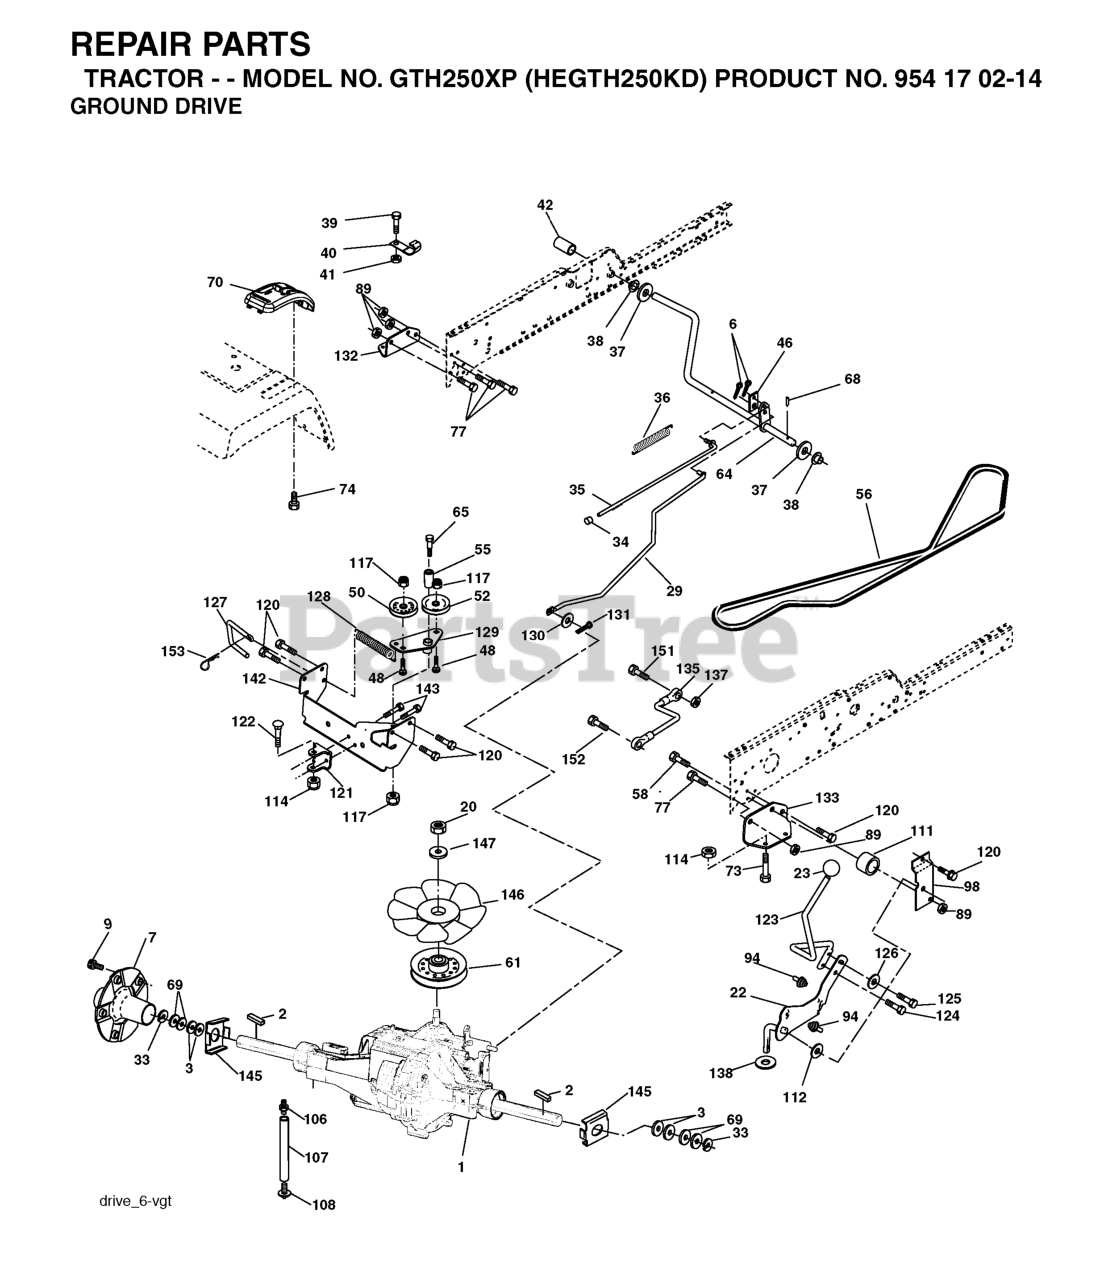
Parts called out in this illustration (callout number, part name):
2	KEY 1/4 X 2.5
6	COTTER PIN
7	HUB ASMBLY
20	NUT.HEX.1/2-20
22	LOWER SHIFT LEVER ASM
23	KNOB.DELUXE.(PISTOL.GRIP).BLAC
29	BRAKE, ROD
33	E RING HYT
34	PLUNGER CAP
35	PARKING BRAKE ROD
36	SPRING DRIVE GROUND
39	Screw, Fin. #10-24 x 1
40	ACTUATOR INTERLOCK SWITCH
41	Nut Centerlock 10-24 unc
42	PEDAL COVER
46	RETAINER SPRING
50	FLAT IDLER PULLEY
52	IDLER PULLEY
55	BEARING LT (2 2)
56	BELT, V GROUND DRIVE
58	BOLT.HEX.7/16-14.FINISHED
61	PULLEY, TRANSAXLE
64	SHAFT.ASM.PEDAL.BRAKE
65	BOLT.SHLDR.3/8-16
68	ROLL PIN STD
70	CONSOLE AUTOMATIC YT.GT
73	BOLT HEX FLGHD 5/16-18X3 GR. 5
74	SCREW.HI-LO.CONSOLE
77	BOLT FIN HEX 7/16-14 X 1
89	Nut, Crownlock Hex 7/16-14 unc
94	FASTENER.XMAS.TREE
98	SHIFT BRACKET
106	O-RING KIT 70110
107	LINE.VENT.HYDRO-GEAR
108	CAP, VENT ASSY
111	SPACER SHIFT LEVER VGTH
112	WASHER NYLON HIGH TEMP
114	NUT.71038.31-18.HEX.NYLOCK
117	NUT LOCK FLG 3/8-16 UNC
120	SCREW, 3/8-16X3/4
121	BRACKET STRAP TORQUE
122	BOLT.5/16-18X2.5
124	BOLT.SHOULDER.5/16-18X
125	CAPSCREW.HXHD.FLG.5/16-18X.625
126	WASHER.SRRTD.5/16
127	LINK CONTROL CLUTCH
128	SPRING DRIVE GRND
129	BRACKET ARM IDLER TENSIONING
131	COTTER PIN
132	BRACKET MTG HYDRO 3500 LH VGT
133	BRACKET MTG HYDRO 3500 RH VGT
135	LINK ASM CONTROL HYDRO 3500
137	LOCKNUT
138	THRUST WASHER
142	STRAP TORQUE HT-3500
143	SCREW 5/16"
145	WASHER.AXLE.FLANGE.HG-3000
146	FAN 7" HYDRO
151	BOLT
152	BOLT HEX 5/16X1 W/PATCH
153	RETAINER M
